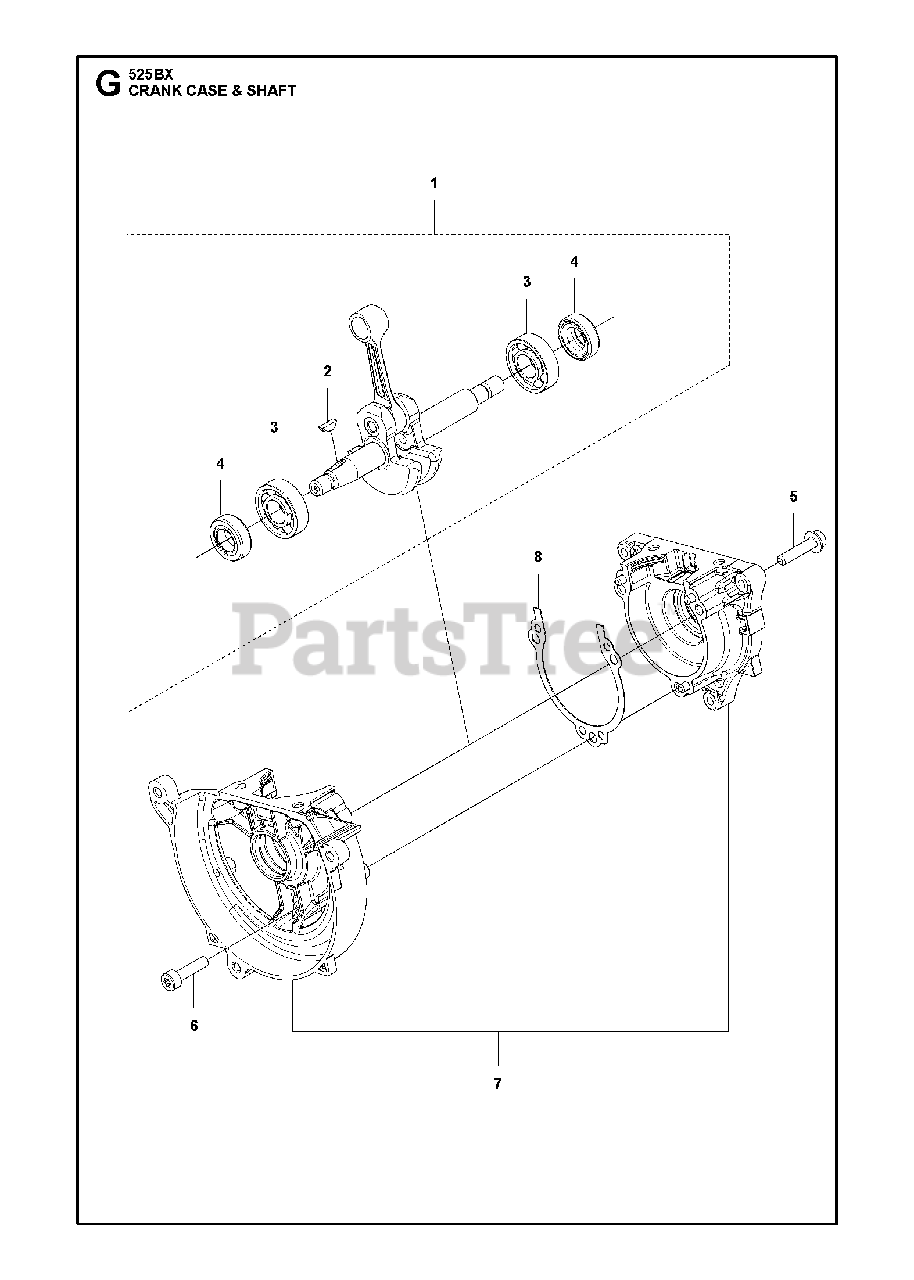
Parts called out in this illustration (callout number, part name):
1	KIT CRANKSHAFT
2	KEY
3	BEARING
4	SEAL
7	CRANKCASE COMP
8	GASKET CASE
